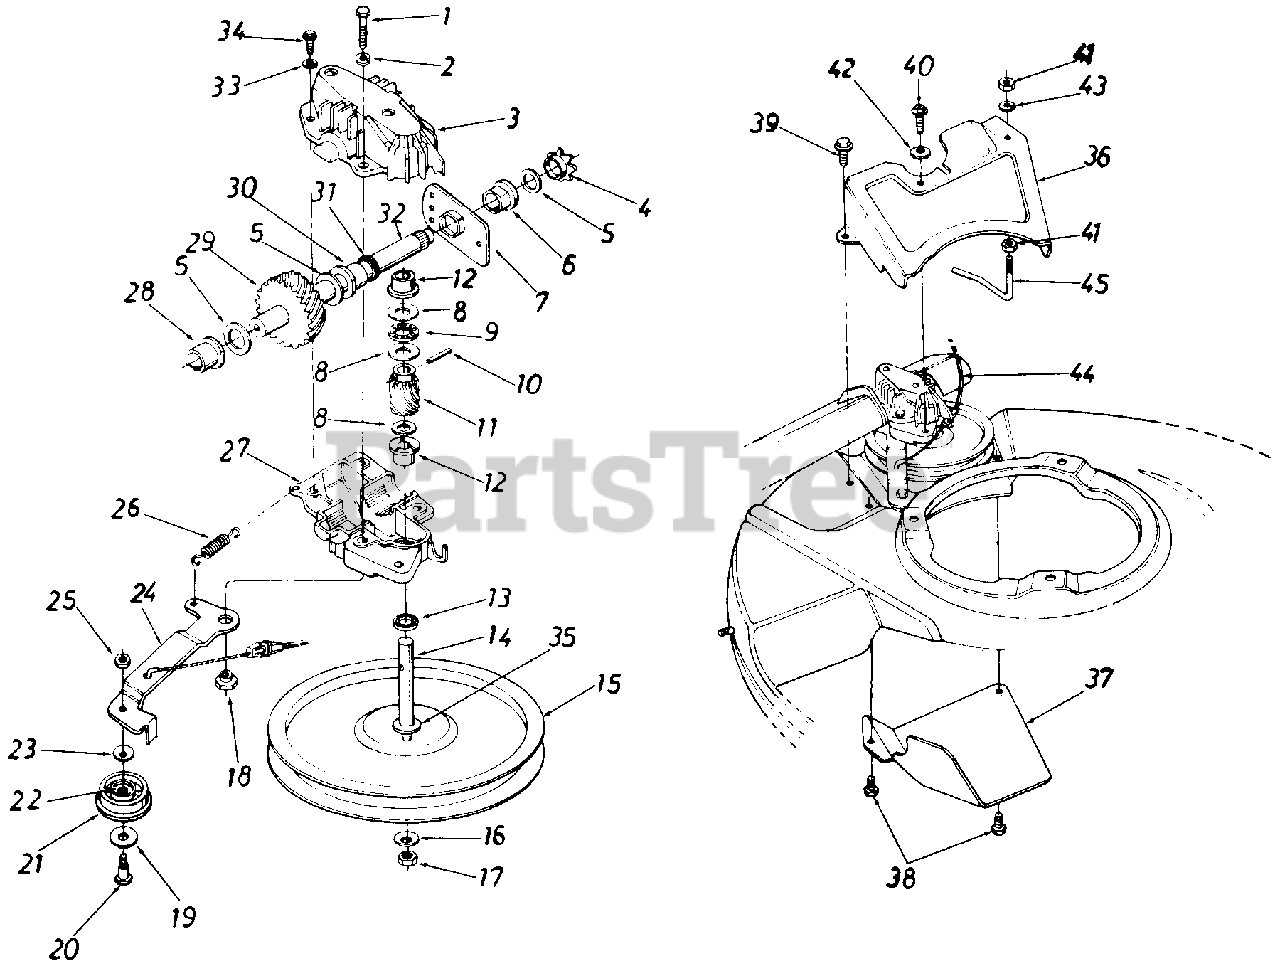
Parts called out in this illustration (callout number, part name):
1	Hex Bolt 1/4-20 x 1.25" Lg.
2	L-Wash. 1/4" I.D.
3	Upper Hsg. Half
4	#48 Sprocket 7 Tooth x 1/2 Pitch
5	Fl-Wash. 5/8" I.D. x .030
6	Hex Flange Brg. .631" I.D.
7	Hex Bearing Cup
8	Thrust Wash. .382" I.D. x .70" O.D.
9	Thrust Bearing .375" I.D. x .812" O.D.
10	Spring Pin Spir. 1/8" x .62" Heavy
11	11 Tooth Helical Gear
12	Flange Bearing
13	Oil Seal
14	Pulley-Transmission Shaft
15	Fl-Pulley 5.06" O.D.
16	Bell-Wash. .265" I.D. x 75"
17	Hex L-Nut 1/4-28 Thd.
18	Shld. Spacer .375" Dia. x .170
19	Fl-Wash. .390" I.D. x 1.0"
20	Shld. Bolt .375" Dia. x .40"
21	Fl-ldler Plastic 1.50" Dia.
22	Needle Brg. .375" x .31
23	Bell-Wash. .265" I.D. x 75"
24	Idler Brk't. Ass'y.
25	Hex Patch L-Nut 1/4-28 Thd.
26	Extension Spring 1.12" Lg.
27	Lower Hsg. Half
28	Flange Bearing .566 Dia.
29	33 Tooth Helical Gear
30	Flange Bearing .629 Dia.
31	Oil Seal .625 Dia.
32	Gear Sprocket Shaft
33	L-Wash. #10 I.D.
34	Hex B-Tap Scr. #10 x .62"
35	Hex Washer .26" x .88"
36	Transmission Belt Guard
39	Hex AB-Tap Scr. 1/4 x .50" Lg.
40	Hex B-Tap Scr 1/4 x 62" Lg
41	Hex Nut 1/4-20 Thd.
42	Bell-Wash. .265" I.D. x 75"
43	L-Wash. 1/4" I.D.
44	S.P. Cable-48" Lg
45	S.P. Belt Guard
